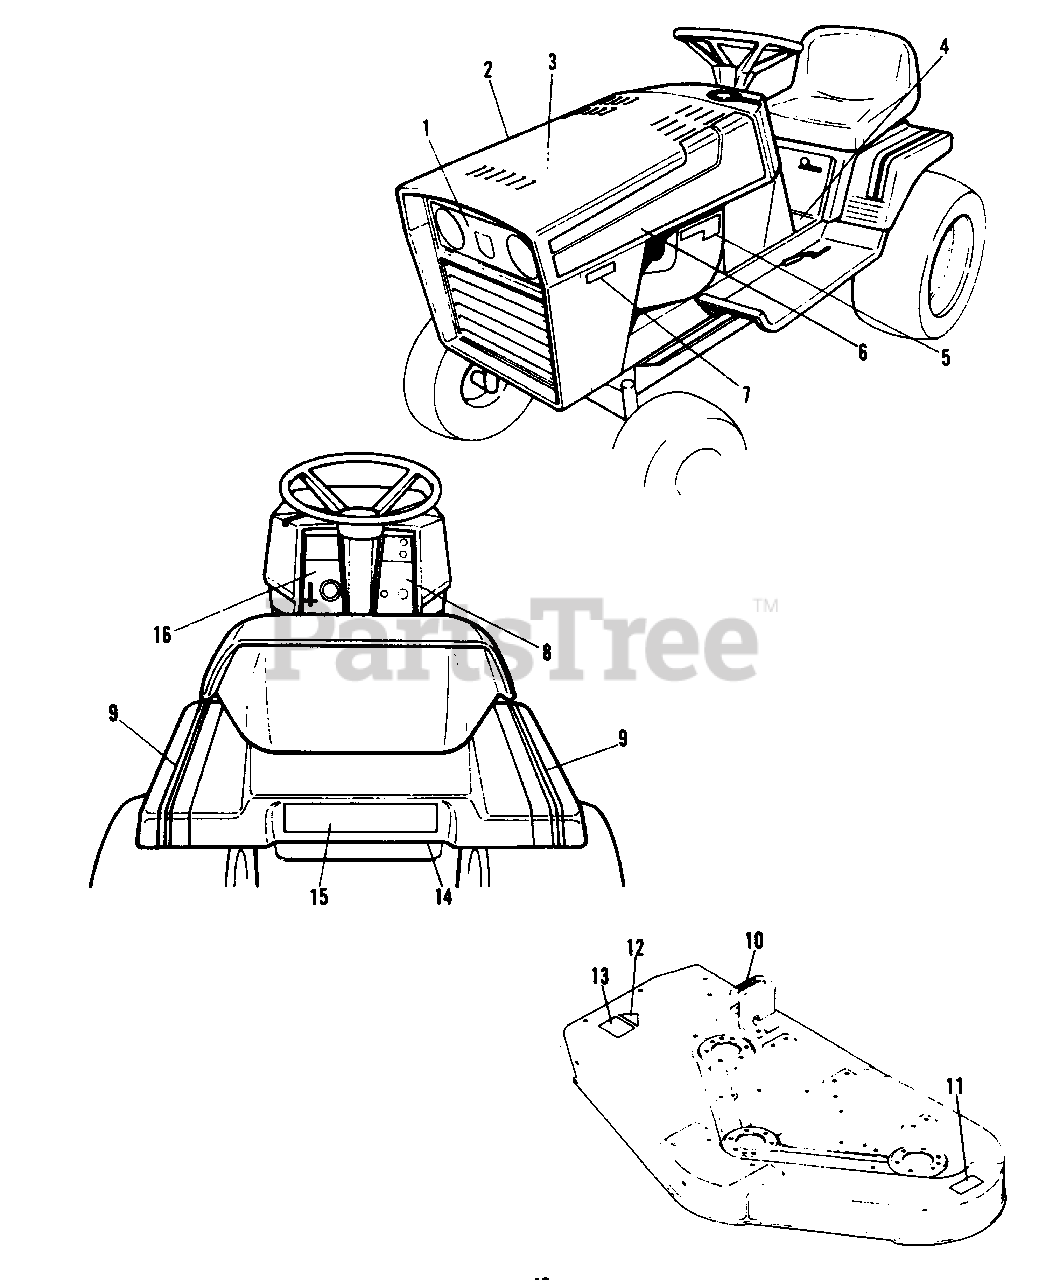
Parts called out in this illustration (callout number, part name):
1	DECAL, Grille
2	DECAL, Hood Stripe, R.H.
3	DECAL, Drive Belts (6116 & 6118)
3	DECAL, Drive Belts (6108 & 6111 Only)
4	DECAL, Shift Pattern
5	DECAL, Twin 16 (6116 only)
5	DECAL, Twin 18 (6118 only)
6	DECAL, Hood Stripe, L.H.
7	DECAL, 6118
7	DECAL, 6116
7	DECAL, 6111
7	DECAL, 6108
8	DECAL, Dash, R.H. (6116 & 6118)
8	DECAL, Dash, R.H. (6108 & 6111)
9	DECAL, Seat Deck
10	DECAL, Mower Height
11	DECAL, Danger
12	DECAL, OPEI
13	DECAL, Warning
14	DECAL, Battery
15	DECAL, Simplicity
16	DECAL, Dash, L.H. (6116 & 6118)
16	DECAL, Dash, L.H. (6108 & 6111)
